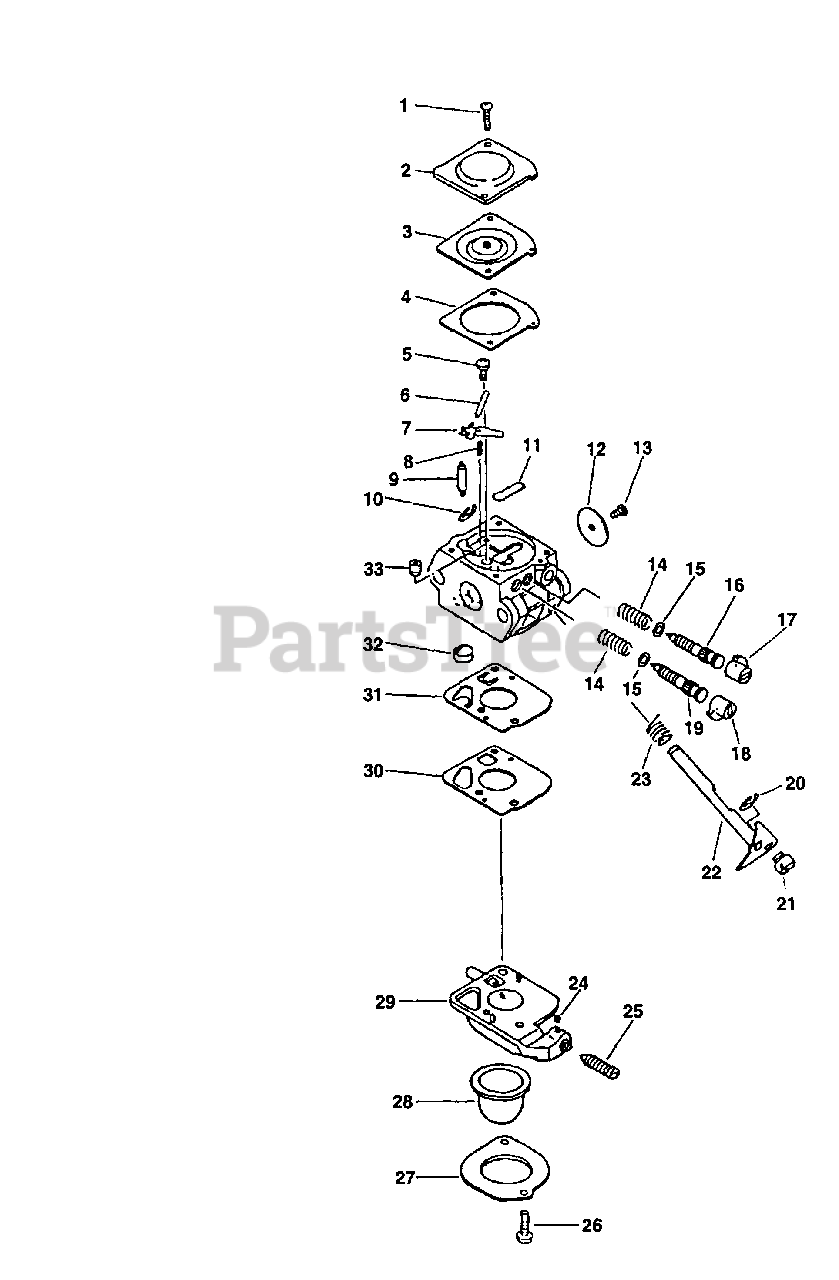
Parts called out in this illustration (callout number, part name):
2	COVER, METERING
3	DIAPHRAGM, METERING
4	GASKET, METERING
5	SCREW, METERING LEVER PIN
6	PIN, METERING LEVER
7	LEVER, METERING
8	SPRING, METERING LEVER
9	VALVE, INLET NEEDLE
10	RING, RETAINING
11	PLUG, WELCH
12	VALVE, THROTTLE
16	NEEDLE - LOW SPEED
17	CAP, LIMITER
18	CAP, LIMITER
19	NEEDLE - HIGH SPEED
20	RING, RETAINING
22	SHAFT, THROTTLE
23	SPRING, RETURN
24	PIECE, FRICTION
25	SCREW, IDLE ADJUST
26	SCREW, RETAINER
27	RETAINER, PURGE BULB
28	BULB, PURGE
29	BASE, PURGE
30	GASKET, PUMP
31	DIAPHRAGM, PUMP
32	STRAINER
33	NOZZLE, CHECK VALVE
